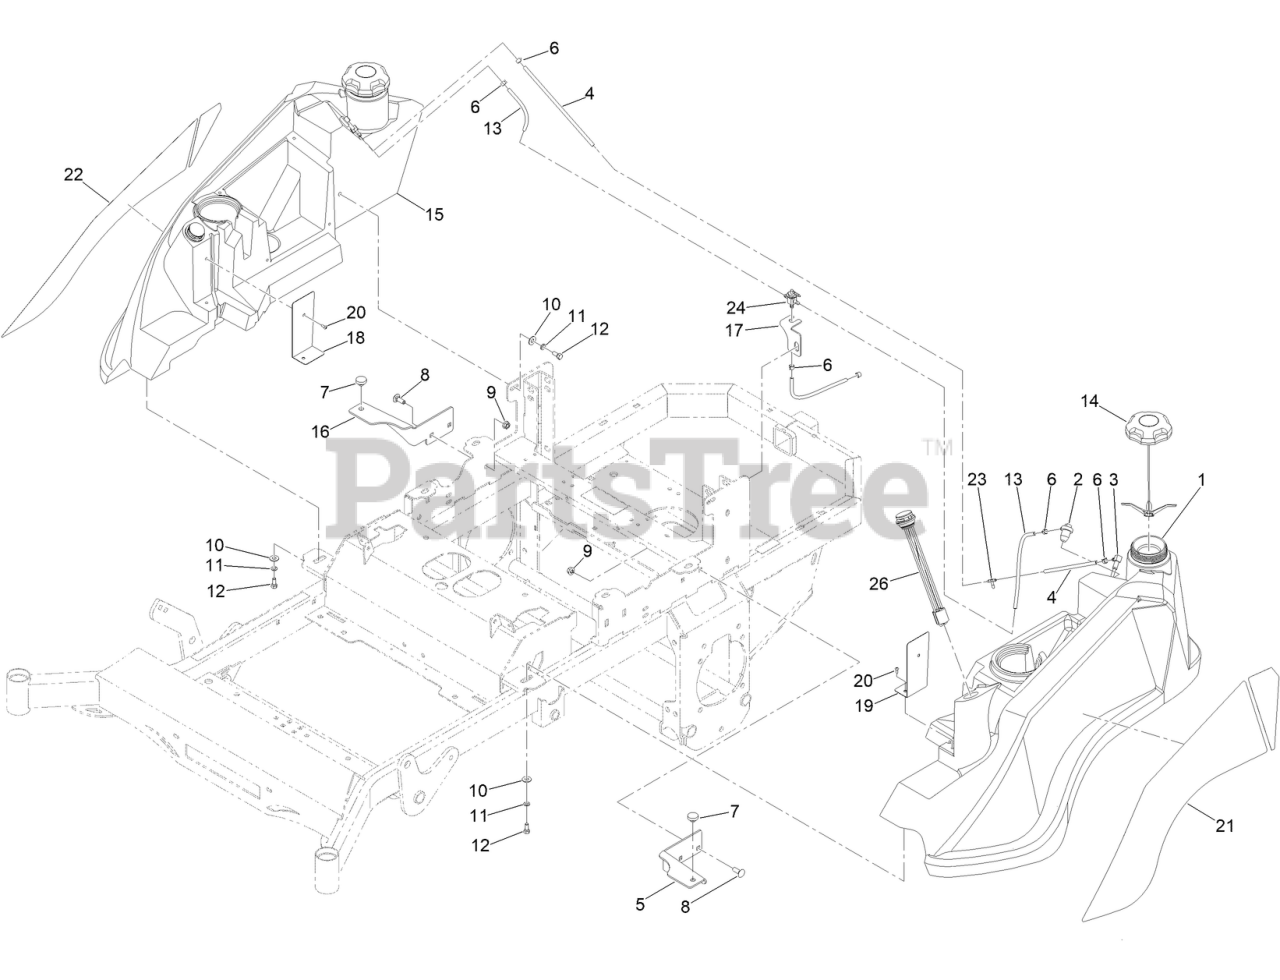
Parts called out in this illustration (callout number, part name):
1	KGZ-XD LT TANK ASSY
2	REMOTE TANK VENT VALVE W/GROMMET
3	KGZ-XD PICK UP TUBE
4	MWR FUEL TANK BLACK 3/16IN VENT TUBE 1FT
5	2022 KGZ LT TANK BRKT BLACK
6	1/2IN (#8) HOSE CLAMP
7	PUSH-IN RUBBER BUMPER MWR FLOOR
8	3/8-16 X 1 CARRIAGE BOLT YZ GR.8
9	3/8-16 HEX FLANGE NUT W/SERR ZINC YELLOW
10	WASHER-FLAT
11	WASHER-LOCK
12	SCREW-HH
13	1/4IN SAE J30R7 BULK HOSE 1FT
14	KELCH TANK FILL NECK NON-VENTCAP(204541)
15	TANK W/ CUPHOLDER
16	2022 KGZ RT TANK BRKT BLACK
17	KGZ FUEL SELECT/SHUTOFF VLV BRKT PAINT
18	KGZ FUEL GAUGE WIRE COVER RT BLACK
19	KGZ FUEL GAUGE WIRE COVER LT BLACK
20	10-24 X 1/2 BUTTON SOCKET BLACK
21	DECAL-TANK
22	DECAL-TANK
23	STAND-ON FUEL LINE T-CONN (3/16IN X 3IN)
24	STAND-ON FUEL SELECTOR/SHUT OFF VALVE
26	KGZ-XD FUEL GAUGE
